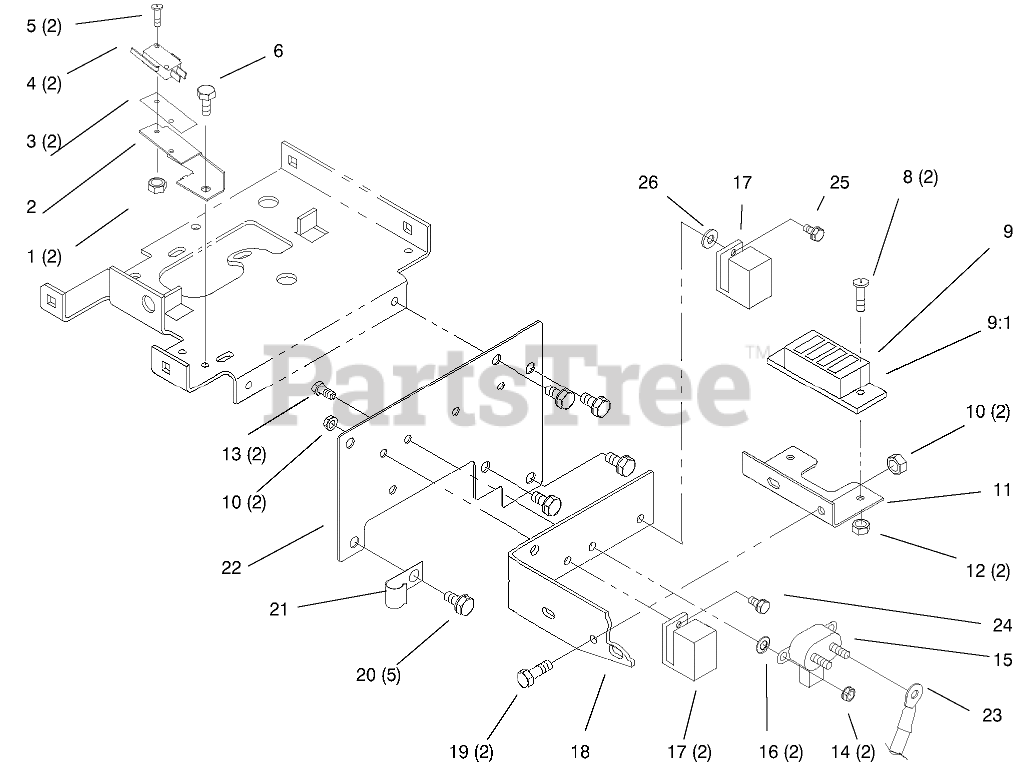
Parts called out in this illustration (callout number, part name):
1	NUT-HEX
2	BRACKET-SWITCH
3	BARRIER - SWITCH
4	SWITCH
5	SCREW-PHL 4-40X1 1/4
6	SCREW-HWH
8	SCREW-PAN
9	WIRING-HARNESS & DIA
9:1	FUSE-HOLDER 4 WAY
10	NUT-LOCK, NI
11	FUSE HOLDERB
12	Nut
13	SCREW1/4-20X5/8 WHIZ
14	NUT-HEX
15	Solenoid
16	WASHER-LOCK/EXT
17	RELAY
18	BRACKET-BELTB
19	SCREW-HH
20	Bolt
21	CLIP
22	Front Plate
23	ASSY WIRE
24	SCREW-HHF
25	SCREW-HHF
26	WASHER-FLAT
